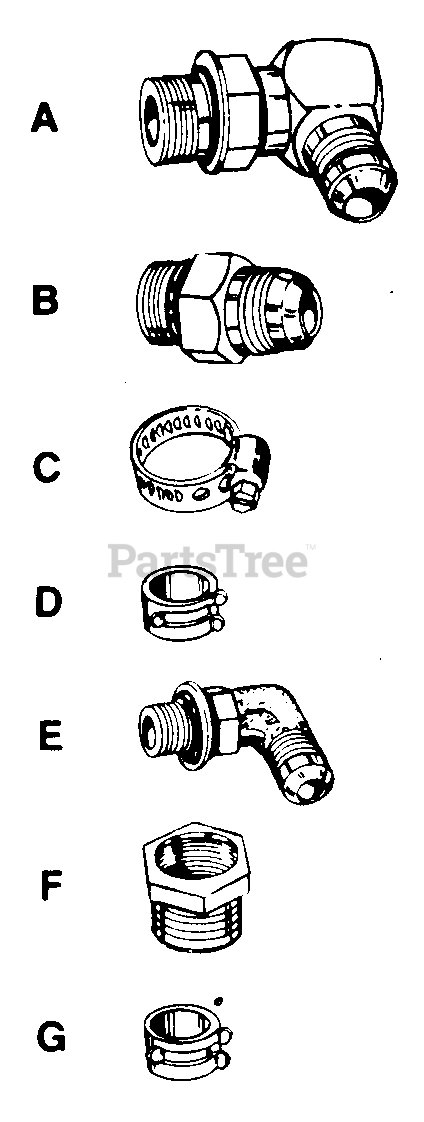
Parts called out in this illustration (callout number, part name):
A	7.8-14 SAE Boss to 3/4-16 JIC.
B	Adapater-"O"-Ring, Boss to Male JIC.
C	Hose Clamp .406 Dia.
D	Hose Clamp 3/8" Dia.
E	1/2-20 SAE Boss to 1/2-20 JIC.
F	Pipe Reducer 1/2-14 to 3/8-18 NPT
G	Hose Clamp .37 Dia. Finish-Green Paint
